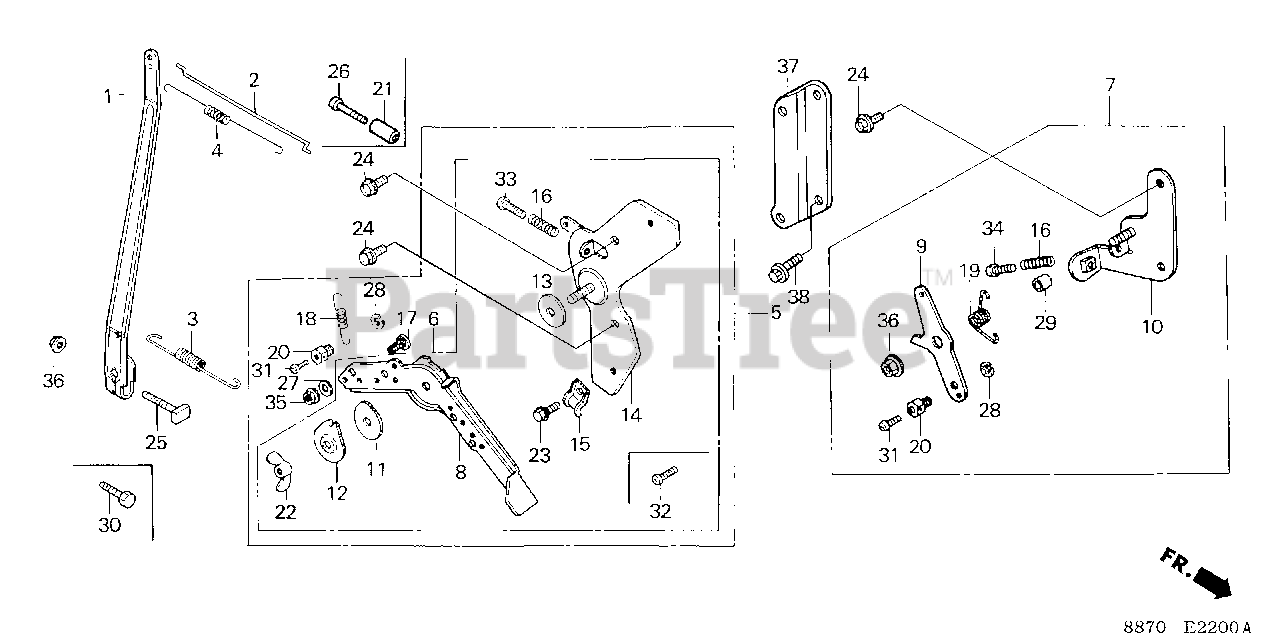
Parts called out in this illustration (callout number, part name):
1	ARM, GOVERNOR
2	ROD, GOVERNOR
3	SPRING, GOVERNOR
4	SPRING, THROTTLE RETURN
5	CONTROL ASSY.
8	LEVER, CONTROL
11	SPRING, LEVER
12	WASHER, CONTROL LEVER
13	SPACER, CONTROL LEVER
14	BASE, CONTROL LEVER
15	HOLDER, CONTROL CABLE
16	SPRING, CONTROL ADJUSTING
22	WINGNUT (6MM)
23	BOLT, FLANGE (5X10)
24	BOLT, FLANGE (6X12) (CT200)
25	BOLT, GOVERNOR ARM
30	BOLT, HEX. (6X20)
32	SCREW, PAN (5X10)
33	SCREW, PAN (5X22)
36	NUT, FLANGE (6MM)
